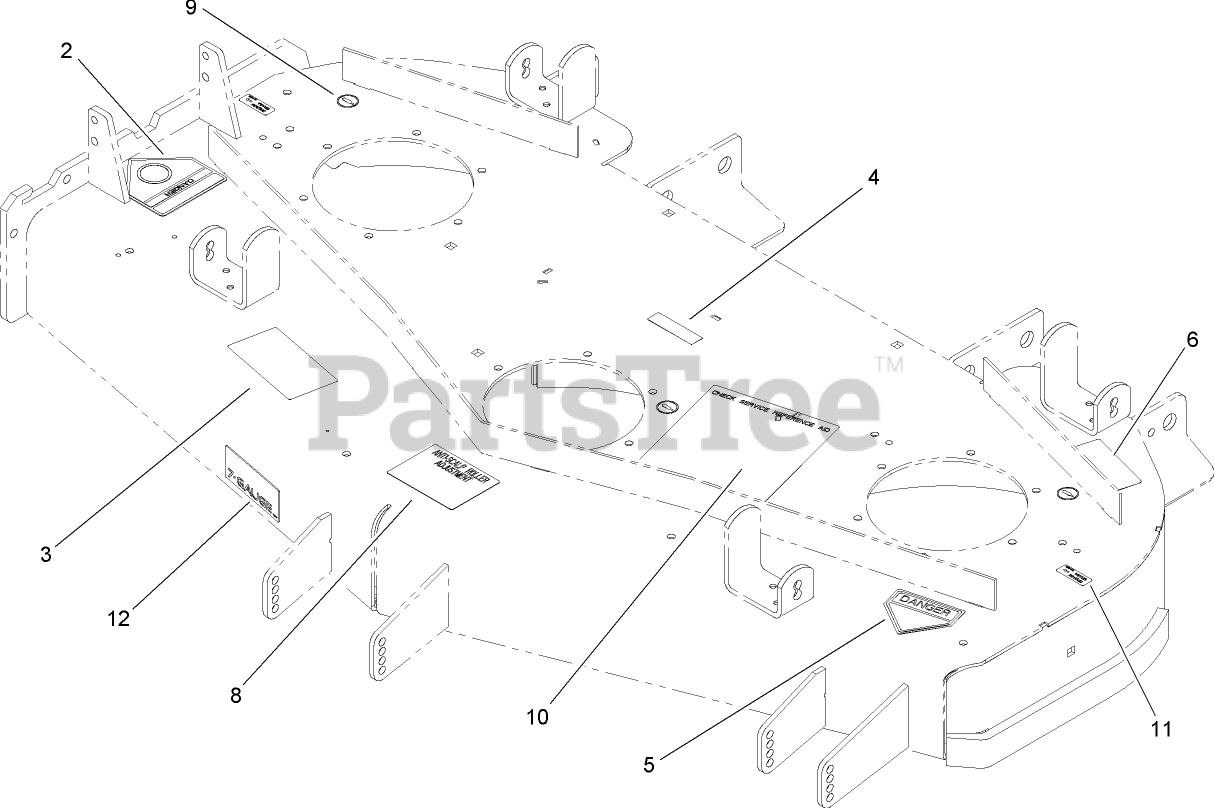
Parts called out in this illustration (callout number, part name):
2	DECAL-DANGER
3	DECAL-DANGER, THROWN OBJECT
4	DECAL-COVER, MISSING
5	DECAL-DANGER
6	DECAL-TORQUE
8	DECAL-SCALP, ANTI
9	DECAL-GREASE
10	Decal-Service, Check
11	Decal-Grease
